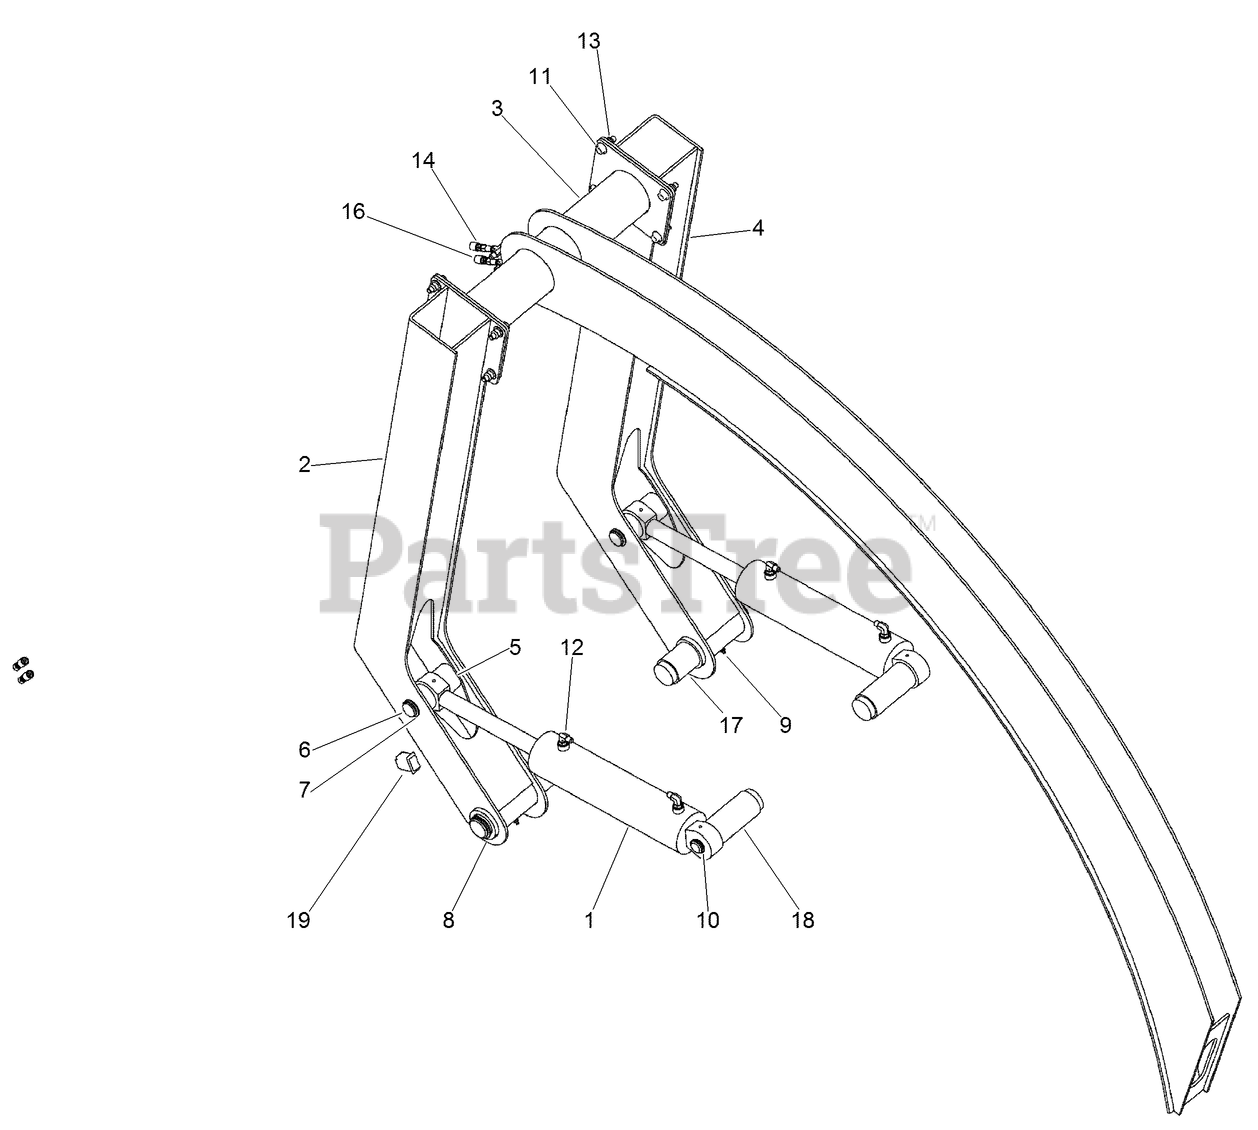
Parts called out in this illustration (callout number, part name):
1	CYLINDER ASSEMBLY - 89 (3-1/2) ID x 290 mm (11-13/32 inch) Stroke, Plow Lift
2	ARM - Crumber
3	GUARD - Crumber
4	ARM - Crumber
5	BUSHING - Pivot
8	RING-RETAINING, EXTERNAL
9	FITTING-Lube 1/8-27 Dryseal PTF
10	RING-RETAINING
12	ELBOW-90 DEG (ADJUSTABLE 37 DEG)
13	NUT-HHF, LOCK
14	TEE - Bulkhead BR 37FL 3/8 x 3/8 x 3/8
16	FITTING
19	SWITCH-ROCKER, 2 POLE
